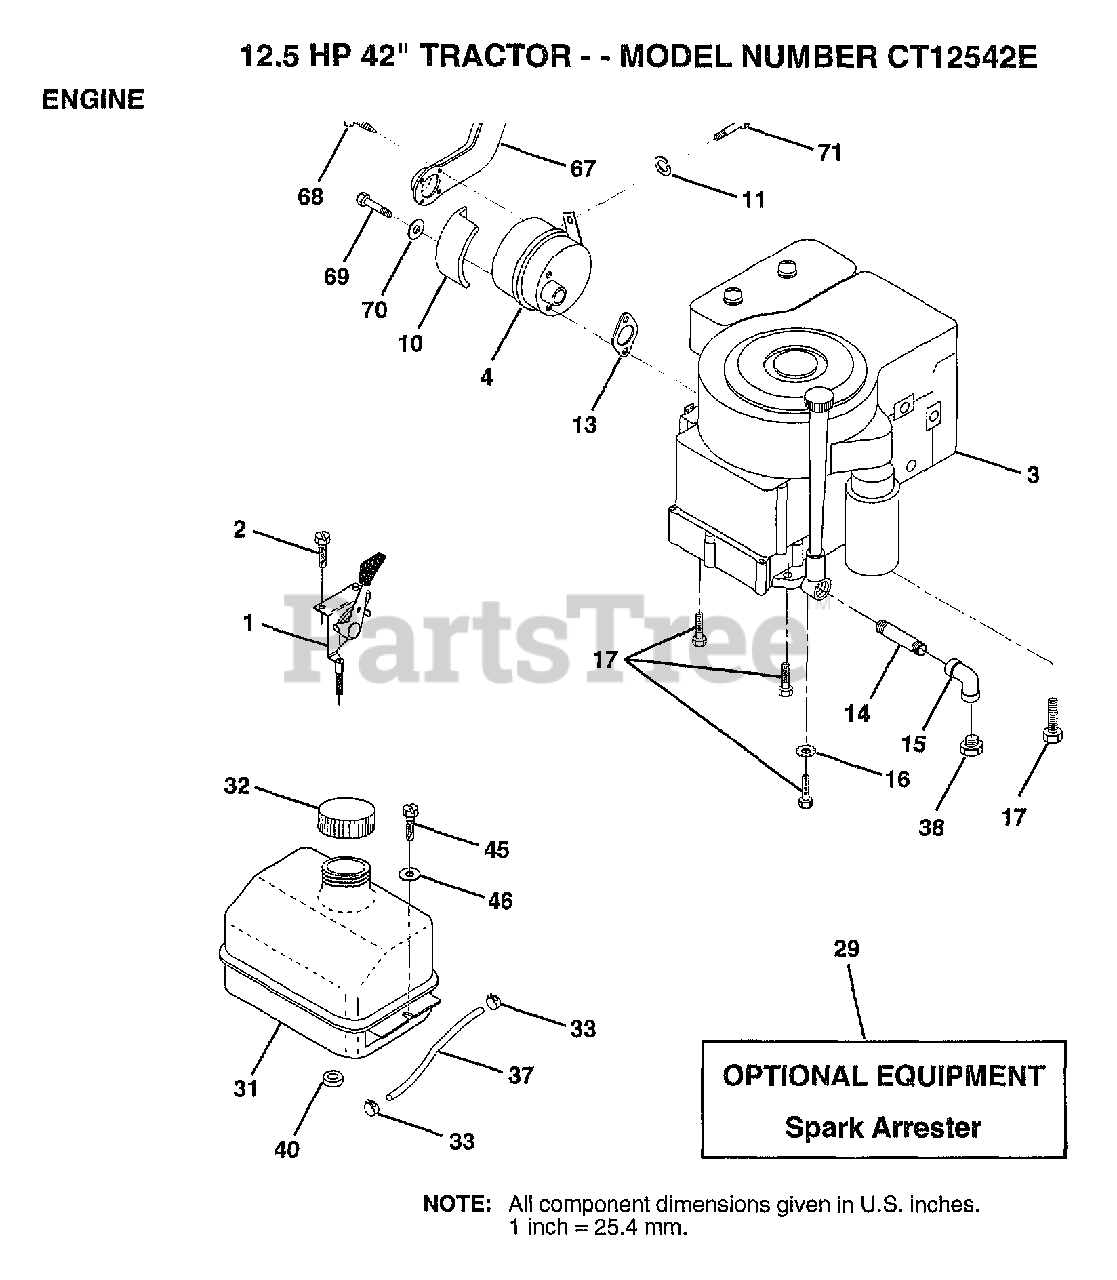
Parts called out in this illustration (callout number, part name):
1	THROTTLE CONTROL
2	SCREW LT
4	MUFFLER LTV
10	SHIELD HEAT LTV
11	LOCKWASHER
14	PIPE NIPPLE
15	ELBOW
16	LOCKWASHER
17	SCREW
31	TANK.FUEL.LT.
32	CAP ASM FUEL
33	HOSE CLAMP
37	LINE FUEL
45	SCREW HEX CRT
46	WASHER
67	DEFLECTOR MUFFLER
69	"BOLT,HEX"
70	WASHER T
71	BOLT
